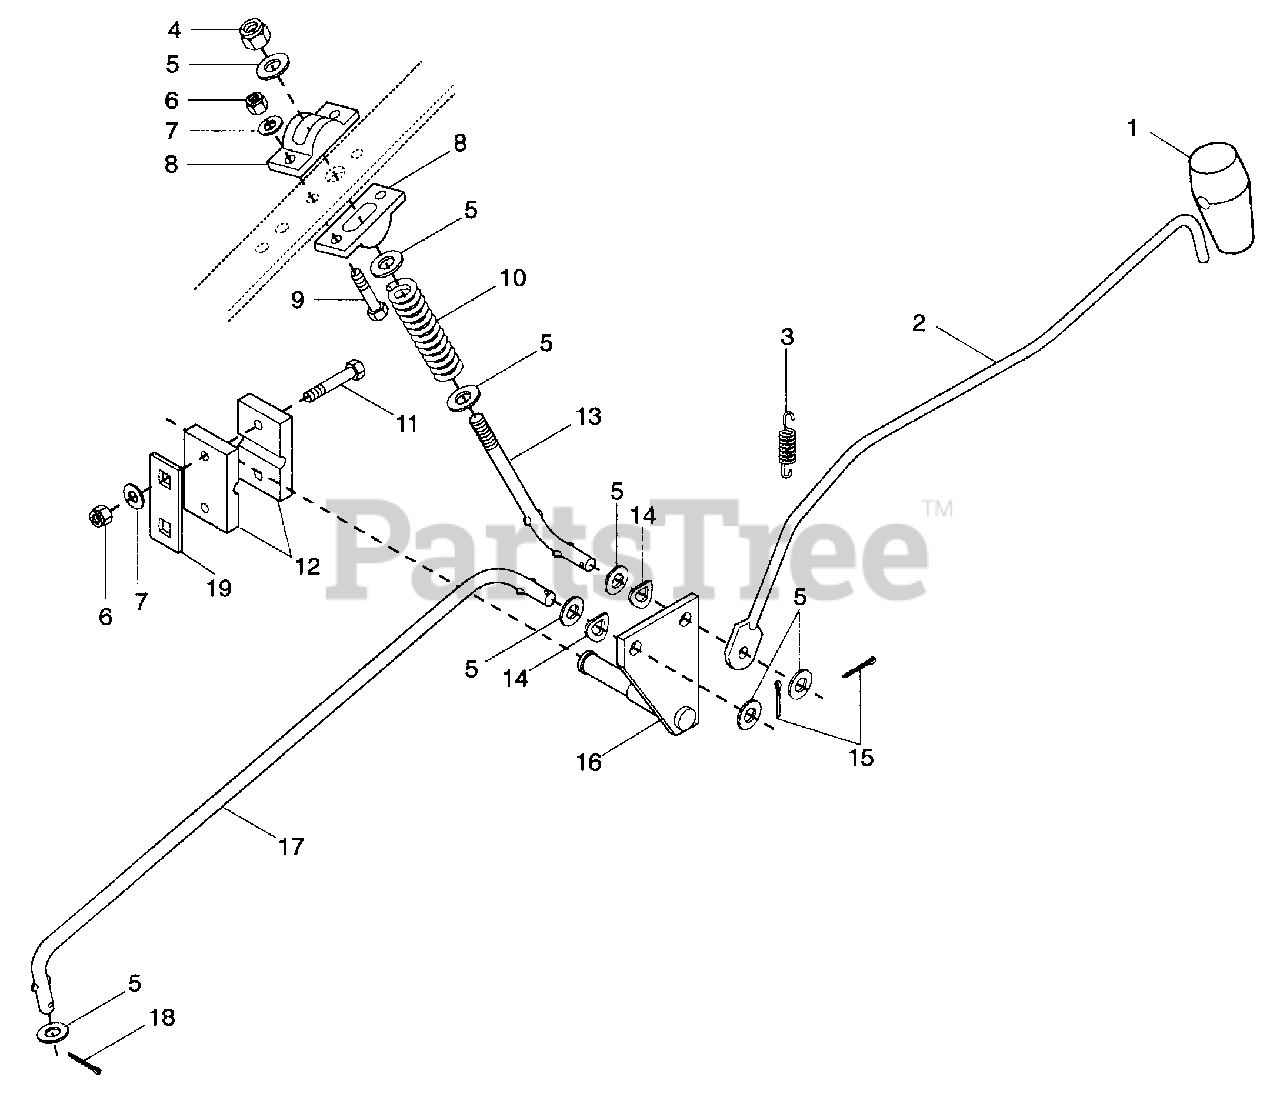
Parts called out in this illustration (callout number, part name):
1	Handle, Rubber Shifter
2	Rod, Shifter
3	Spring-Tension .041 x 1.25 x .50
4	Nut-Locking-Nylon .375-16
5	Washer-Flat-Steel .406 x .812 x .065
6	Nut-Locking-Nylon .250-20
7	Washer-Flat-Steel .281 x .62 x .065
8	Cam, Shifter
9	Bolt-Hex .25-20 x 1.00 Grade 5
10	Spring-Compression .081 x .720 x 2.75
11	Bolt-Hex .25-20 x 1.50 Grade 5
12	Block, Shift Lever
13	Link, Shifter Stop
14	Spring Washer
15	Pin-Cotter .12 x .75
16	Weldment, PTO Bellcrank
17	Link, PTO Control
18	Pin-Cotter .09 x .75
19	Shim, Mower Height Adjuster Bracket
